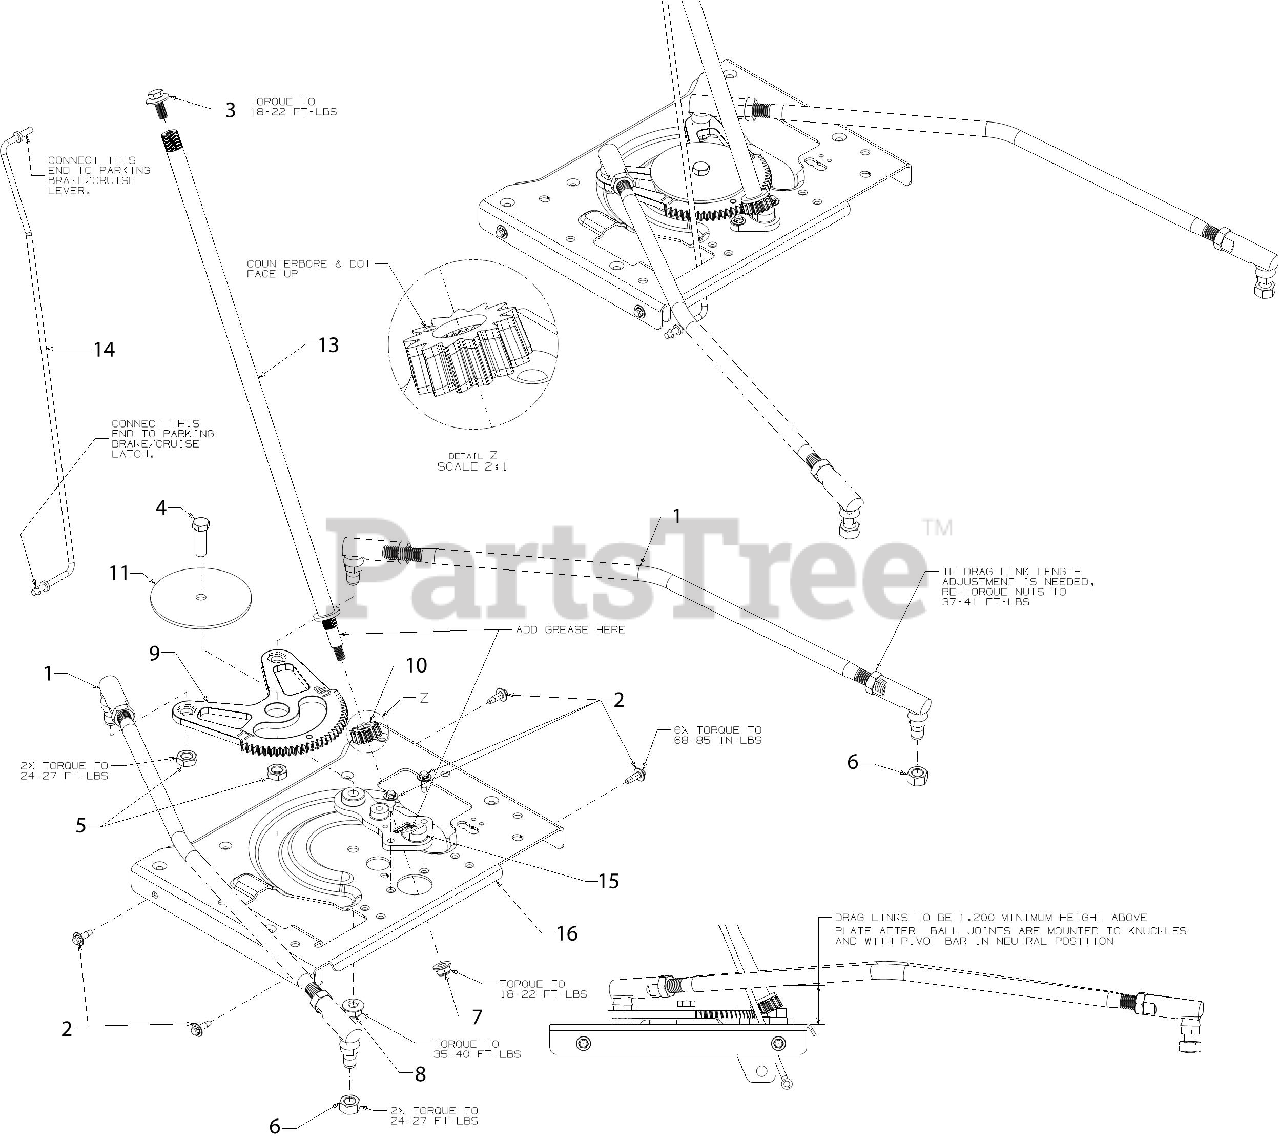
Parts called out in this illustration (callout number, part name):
1	STEERING TIE ROD ASSEMBLY
2	SCREW M6-1 x .625
3	SCREW 5/16-24 x .85 GR5
4	HEX SCREW 3/8-16X1.25
5	JAM NUT 7/16-20
6	HEX NUT FLANGE 3/4
7	FLANGE LOCK NUT 5/16-18
9	STEERING GEAR SEGMENT
10	STEERING PINION GEAR 13T
11	FLAT WASHER .385 x 3.75 x .120 THK
13	STEERING SHAFT .625 x 20
14	CRUISE/BRAKE ROD
15	STEERING SUPPORT PLATE
16	STEERING MOUNTING PLATE
